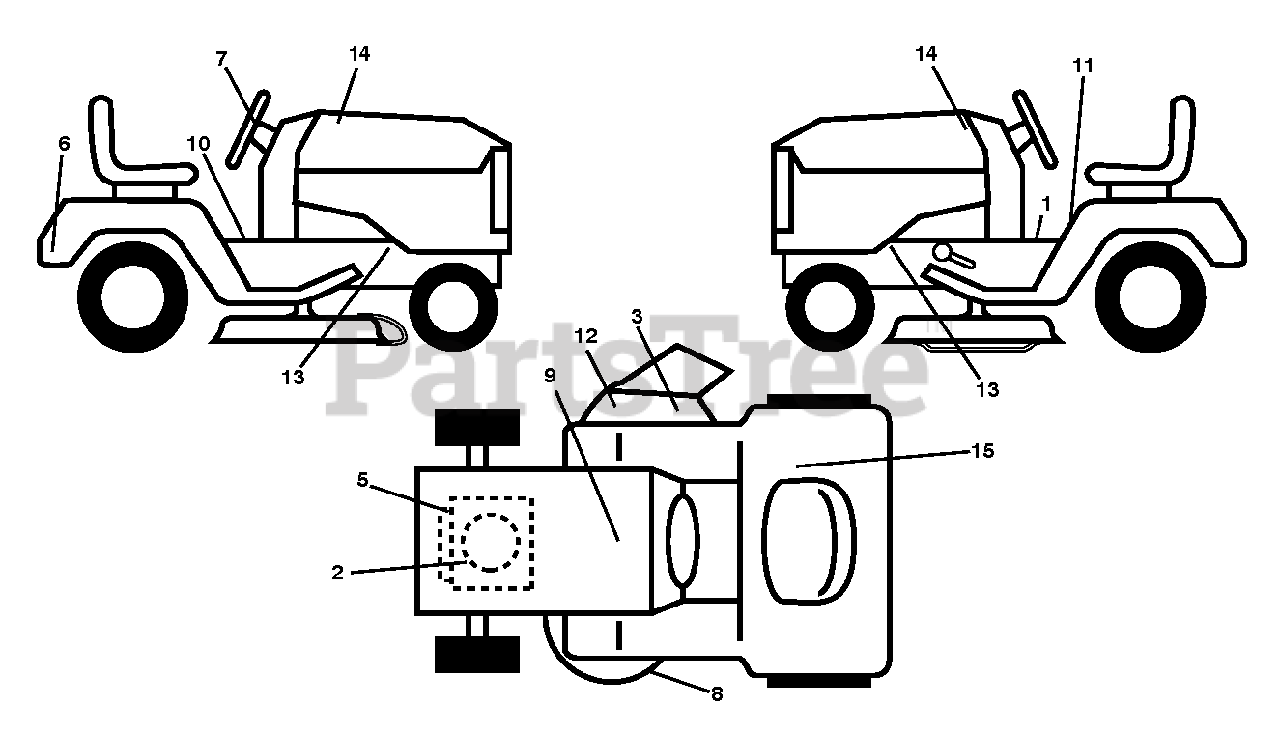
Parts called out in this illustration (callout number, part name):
1	DECAL.PARKING.BRAKE.SADDLE.LT
2	DECAL.ENGINE.WARNING
3	DECAL, DECK DEFLECTOR, WARNING
5	Decal, Engine BS 20INTK DOM 381707
6	DECAL.REARFNDR.POULAN PRO.2015
7	Decal, Steering Wheel STDXXSQ PPRO 2015
8	DECAL.MOWER.SCH.48/54.PREM
9	DECAL BTRY SYMBOLS
10	DECAL.FNDR.SDLE.BRAKE.CLUTCH.6
11	DECAL.READ.OWN.MAN.SYMBOL.LT
12	DECAL.DFLCTR.WARNNG.CTFNGR.SYM
13	DECAL.CHASSIS.HOT.MUFFLER
14	DECAL.POULAN PRO.2015
15	DCL.TRACTOR.CONSUMPTION.MEXI
